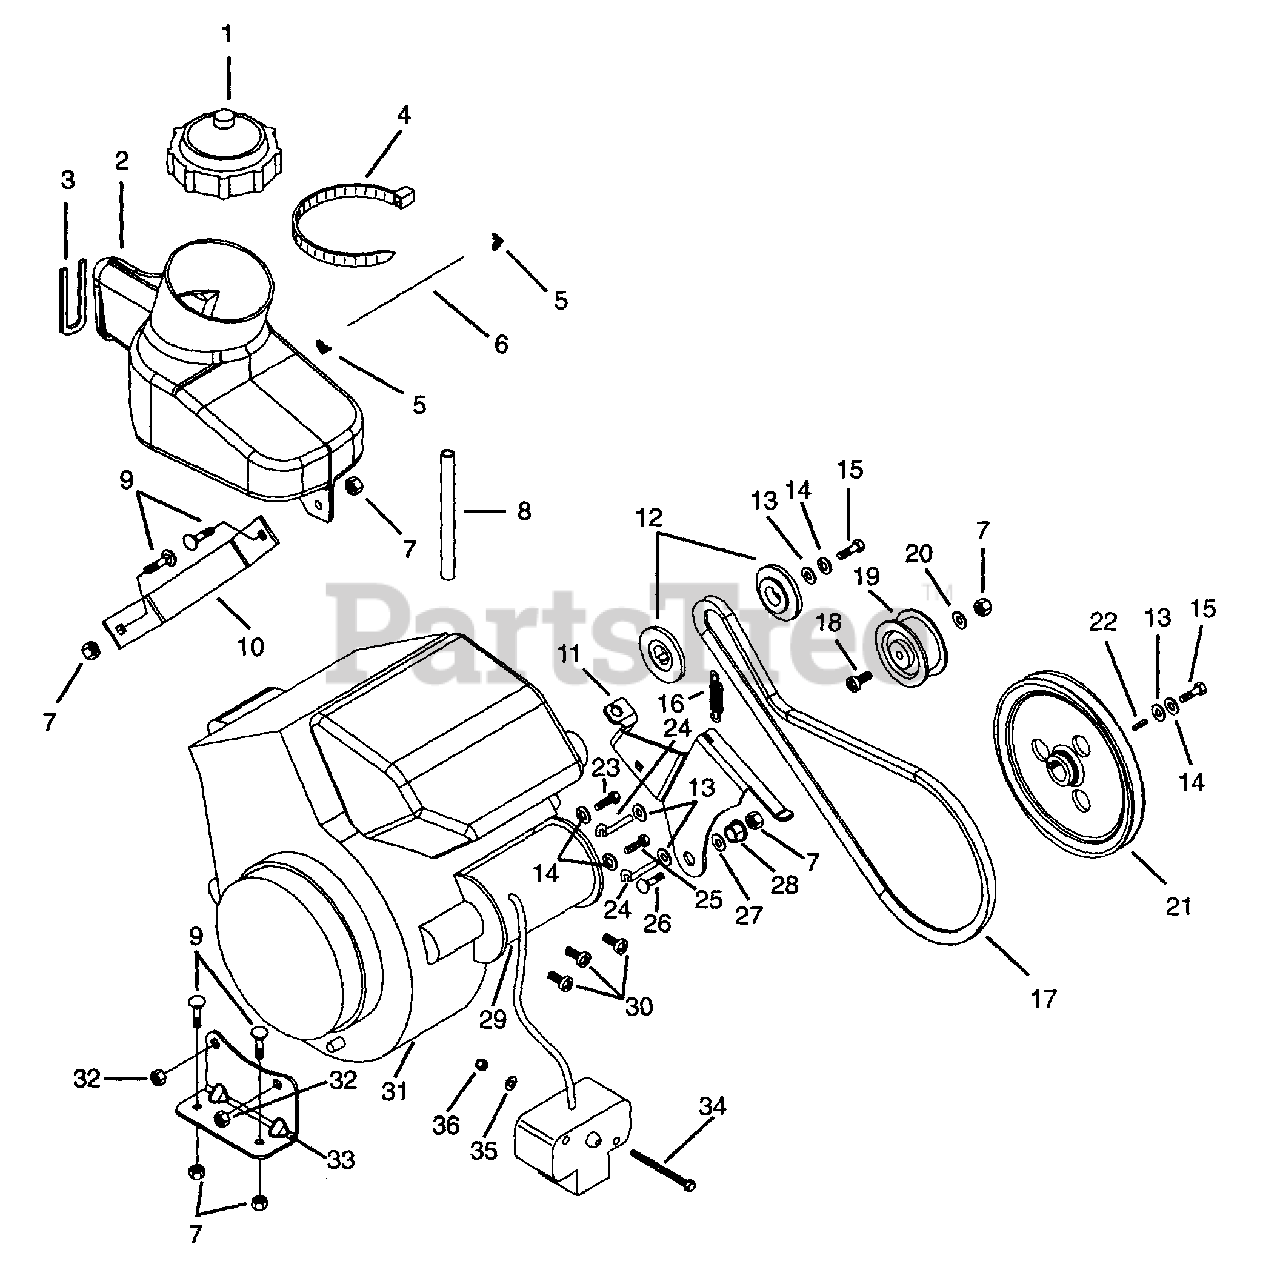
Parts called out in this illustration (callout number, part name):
1	CAP-FUEL
2	TANK-FUEL
3	TAPE FOAM,NEOPRENE
4	TIE WRAP, 15.25" X 120 LBS
5	CLAMP-HOSE WIR.490/.510X.092#8
6	GAS LINE HOSE 1/4 X 11"
7	NUT-LK-FLG .250-20 PL BLK
8	LINE-PRIMER
9	BLT-RDHDSQNK .25-20X.75 GR5PL
10	BRKT-FUEL TANK MTG
11	ARM-IDLER
12	PLY-DRIVE 3LX 1.52 DIA
12	PLY-DRIVE 3LX 1.80 DIA
13	WSHR-FL-STL .328X.875X.062 PL
14	WSHR-LK .313X.078 PL MED
15	BLT-HEX .31-24X.75 PL GR5
16	SG-TENS .051X.60X2.50 WLD 7.0
17	V-BELT, 3L-RAW EDGE
18	BLT-RDHDSQNK .25-20X1.25 GR5PL
19	IDLER-FLAT 1.75 X .27 DAYCO
20	WSHR-FL-STL .281X1.000X.063
21	PLY-IMPELLER SHAFT 3LX 6.0 DIA
22	KEY-SQ .188X.75X.188
23	BLT-HEX .31-18X.75 PL GR2
24	FINGER-BELT
25	BLT-HEX .31-18X1.00 PL GR 2
26	SCR-MCH .25-20X.75 TXTR YWZC
27	WSHR-FL-STL .505X.875X.024 PL
28	BSHG-FLG .265X.437X.250X.750
29	MOTOR-STARTING
30	SCR-HFWH-TX .25-20X.868 TEC#42
30	SCR-HFWH-TX-SEMS .25-20X.49 TE
31	ENGINE-TEC 3HP 2 CYCLE
31	ENGINE-TEC 5HP 2 CYCLE
32	NUT-LK .312-18 GR A PL
33	BRKT-ENGINE MTG
34	SCR-MCH 8-32X2.75 SLRDHD PL
35	WSHR-FL-STL .194X.492X.047 PL
36	@NUT-LK-NYL 8-32 W/INSTR YWZC
